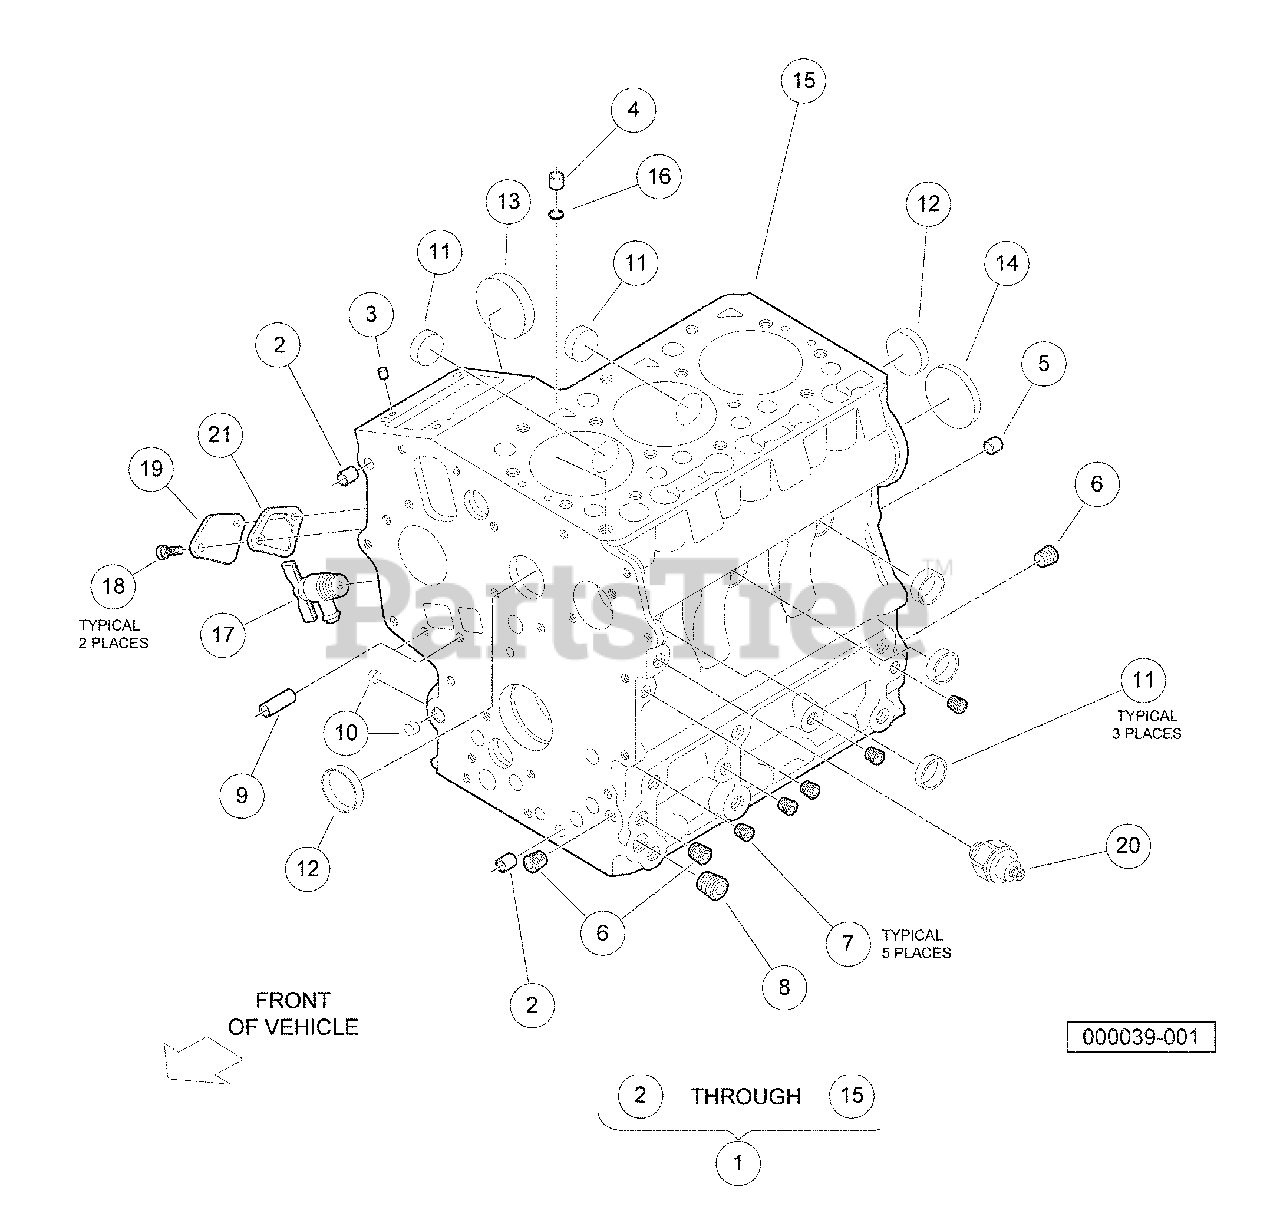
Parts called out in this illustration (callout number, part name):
1	Engine Block
2	Pin, Pipe, Dia 8 X 14
3	Pin, Straight, Dia 5 X 10
4	Pin, Pipe, Dia 7 X 14
5	Pin, Straight, Dia 8 X 16
6	Plug, 1/8"
7	Plug, 3/32"
8	Plug, 1/4"
9	Pin, Pipe, Dia 8 X 11
10	Cap, Sealing, Small
11	Cap, Sealing, Med
12	Cap, Sealing, Large
13	Cover, Fuel Camshaft
14	Plug, Expansion
15	Block, Engine
16	O Ring, 8 X 7
17	Cock, Drain.
18	Bolt, M6 X 1 X 20
19	Plate, Engine Block
20	Switch, Oil Pressure
21	Gasket, Fuel Pump, D722
